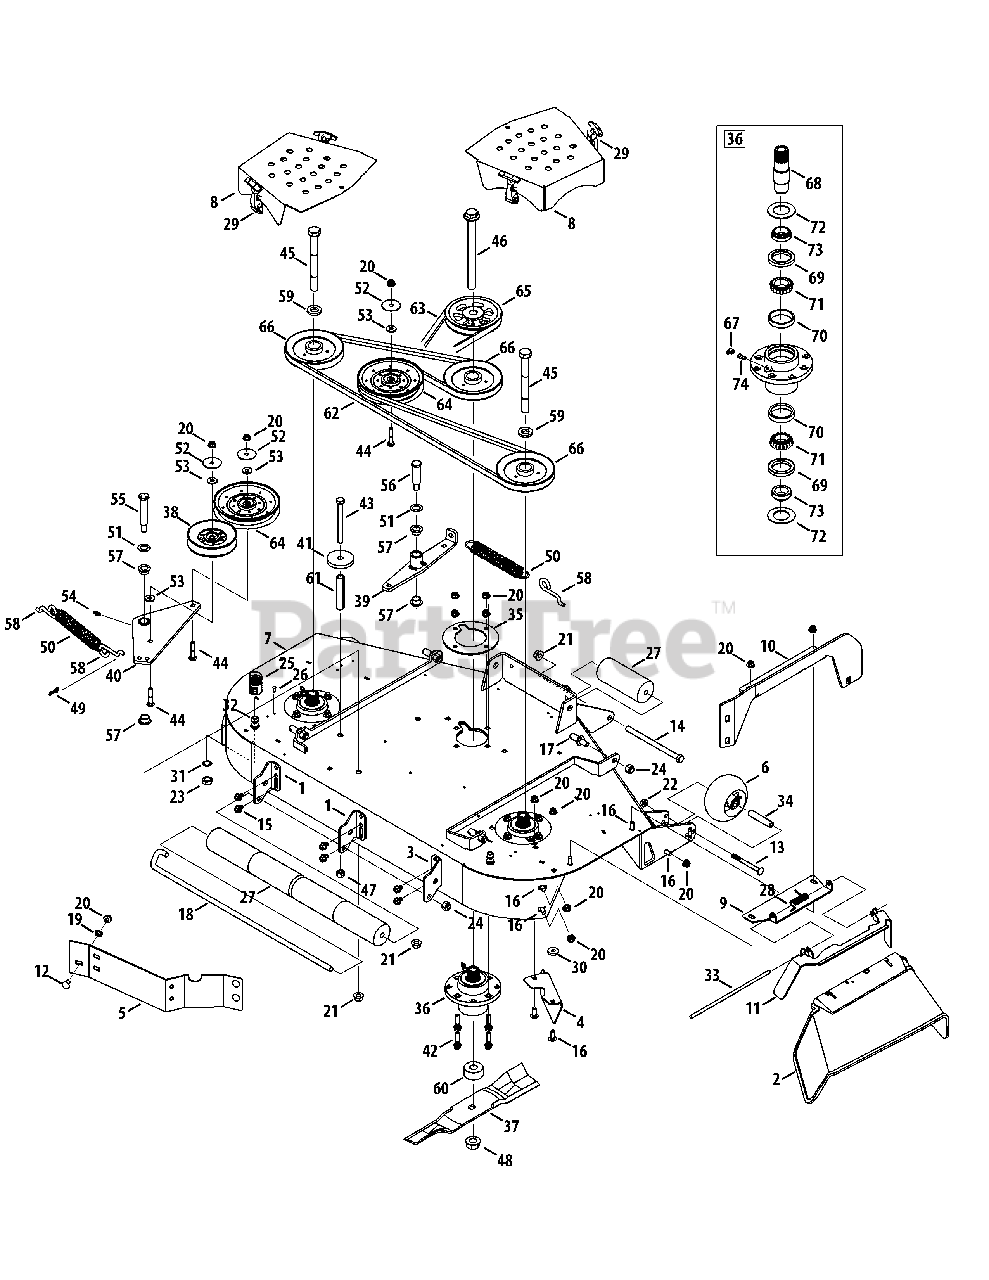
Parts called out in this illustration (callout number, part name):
1	Deck Roller Mount Bracket
2	Chute Deflector
3	Roller Mount Bracket
5	Baffle, 48" Adjustment
6	Complete Wheel, 5.00 Dia.
7	48" Deck Assembly
8	Deck Belt Cover
9	Chute Deflector Bracket
10	Deck Support Plate
11	Chute Extension Bracket
12	Carriage Bolt, 3/8-16 x .750
13	Carriage Bolt, 3/8-16 x 4.00
14	Hex Cap Screw, 1/2-13 x 7.50
15	Screw, 3/8-16 x .500
16	Carriage Bolt, 3/8-16 x 1.00
17	Pin, 1/2-13 x .625 x 1.2
18	J-Hook w/ Threaded Roller
19	Push Nut, 3/8
20	Nut, 3/8-16, Flangelock
21	Nut, 1/2-13, Flangelock
22	Nut, 3/8-16, Flangelock
23	Hex Nut, M16-1.5
24	Nut, 1/2-13, Hexlock
25	Water Nozzle Adaptor
26	Pop Rivet, 3/16
27	Front Roller
28	Torsion Spring, 0.639 x 2.16
29	T-Handle Latch Draw
30	Washer, .395 x 1.12 x .190
31	Lock Washer, 17 x 23.8 x 1.95
32	Deck Water Nozzle
33	Chute Deflector Rod
34	Wheel Spacer
35	Spindle Support Plate
36	Spindle Assembly
37	Hi-Lift Blade, 17.0
38	Idler Pulley
39	Deck Idler Arm
40	Idler Assembly
41	Spacer, .5375 x 2.75 x .375
42	Carriage Bolt, 3/8-16 x 1.5
43	Hex Cap Screw, 1/2-13 x 5.00
44	Carriage Bolt, 3/8-16 x 2.00
45	Hex Cap Screw, 3/4-16 x 7.00
46	Hex Cap Screw, 3/4-16 x 9.00
47	Nut, 1/2-13, Hexlock
48	Nut, 3/4-16, Flangelock
49	Bow Tie Cotter Pin
50	Extension Spring, 1.248 x 8.5
51	Washer, .793 x 1.24 x .06
52	Washer, .406 x 1.92 x .060
53	Washer, .406 x 1.00 x .105
54	Grease Fitting
55	Shoulder Bolt, .75 x 3.25, 1/2-13
56	Shoulder Bolt, .750 x 2.23, 1/2-13
57	Flange Bearing, .75 x .52
58	Spring Rod Hook
59	Spacer, .812 x .218
60	Spacer, .760 x 2.00 x .925
61	Spacer, .405 x .75 x 3.875
64	Idler Pulley
65	Drive Pulley
66	Spindle Pulley
67	Grease Fitting, 45 degree, 1/4-28
68	Spindle Shaft
69	Seal, Oil
70	Cup Bearing
71	Cone Bearing
72	Washer, 1.05 x 2.52 x .076
73	Ring, Seal
74	Straight Adapter Fitting
